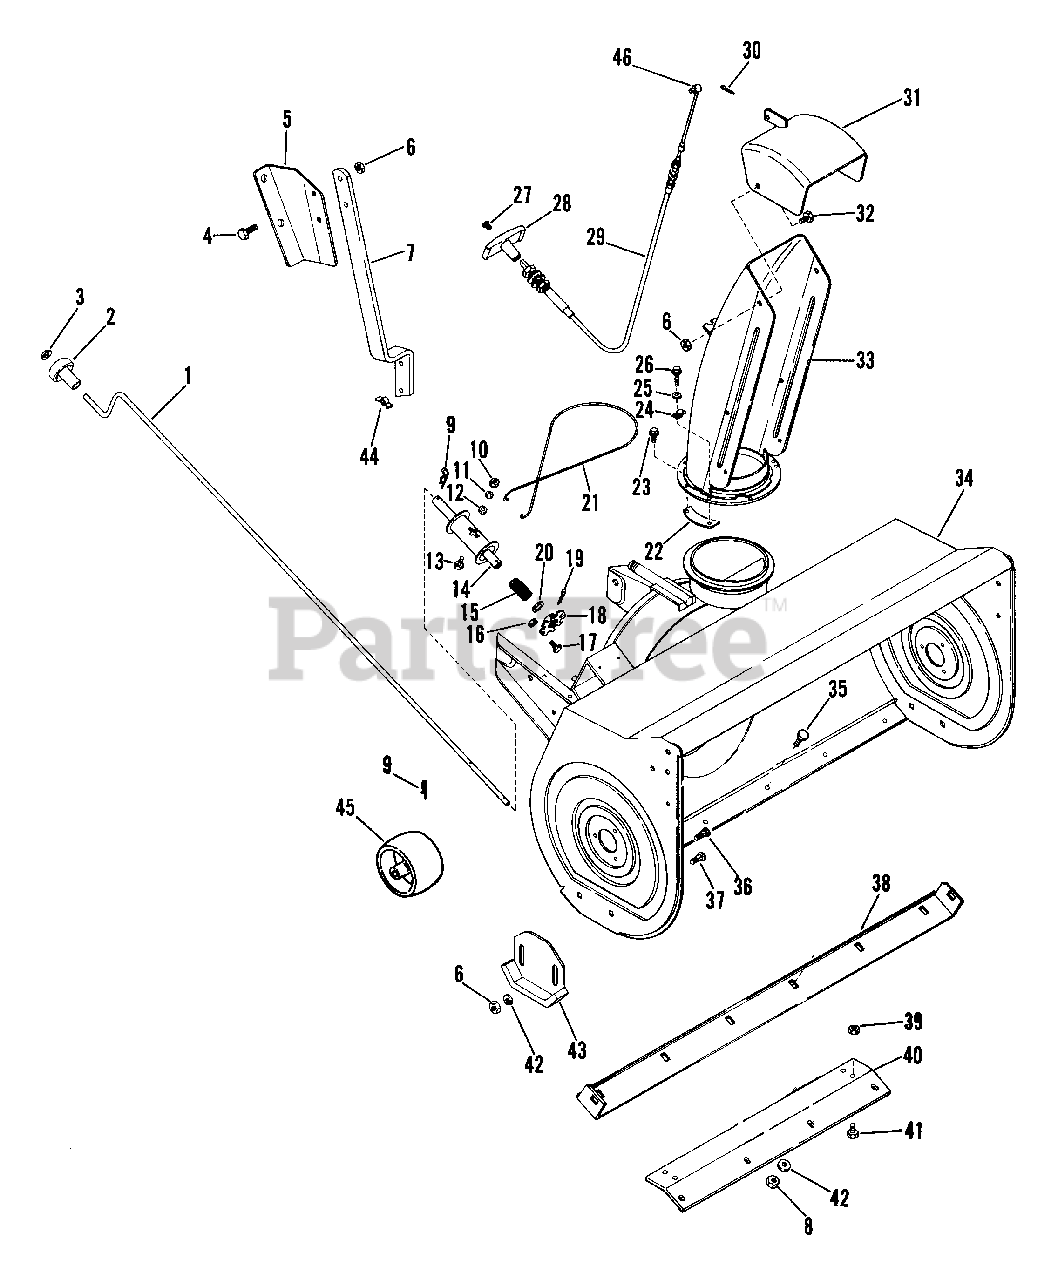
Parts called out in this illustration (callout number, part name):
1	CHUTE CONTROL CRANK
3	RG-RTNG-EXT .500X.015
4	BLT-HEX .38-16X1.00 PL
5	CONTROL BRACKET
6	NUT-LK-CTR .375-16 GR A PL
7	CHUTE CRANK SUPPORT
8	NUT-LK .312-18 GR A PL
9	PIN-HAIR INT .08X.38X1.42 YWZC
10	NUT-HEX .250-20 PL
11	WSHR-LK .313X.062
12	WSHR-FL-STL.281X.62X.065 PL
13	BLT-RDHDSQNK .25-20X.62 PL
14	SPOOL
15	SG-COMP .054X.75X1.6
16	NUT-LK DUAL FACE 10-24 PL
17	SCR-SKH 10-24X.38
18	DISC ASSEMBLY
19	PIN-ROLL .188X1.00
20	WSHR-FL-STL .640X1.005X.062 PL
22	CHUTE CLAMP
23	SCR-TAP 10-24X.484 HWH TR
24	CABLE CLAMP
25	WSHR-FL-STL .188X.438X.049 PL
26	SCR-TAP 10-24X.75 HWH PL TR
27	SCR-MCH 8-32X.75 SLPAN PL
28	KNOB-BLACK
29	CONTROL CABLE
30	PIN-COTR .09X.75 PL
31	DEFLECTOR W/DECAL
32	BLT-HEX .38-16X.75 PL GR2
33	DISCHARGE CHUTE
34	36" SNO THRO HOUSING
35	BLT-RDHDSQNK .31-18X.75 SHT PL
36	BLT-RDHDSQSHNK .38-16X1.00 PL
37	BLT-RDHDSQNK .38-16X.75 SHT PL
38	SCRAPER BLADE 36"
39	NUT-LK TOP .375-16 GR C YWZC
40	BLADE BRACE
41	BLT-HEX .38-16X.75 PL GR5
42	WSHR-FL-STL .38X.875X.083 PL
43	RUNNER-SKID SHOE
44	NUT-WING .312-18 YWZC
